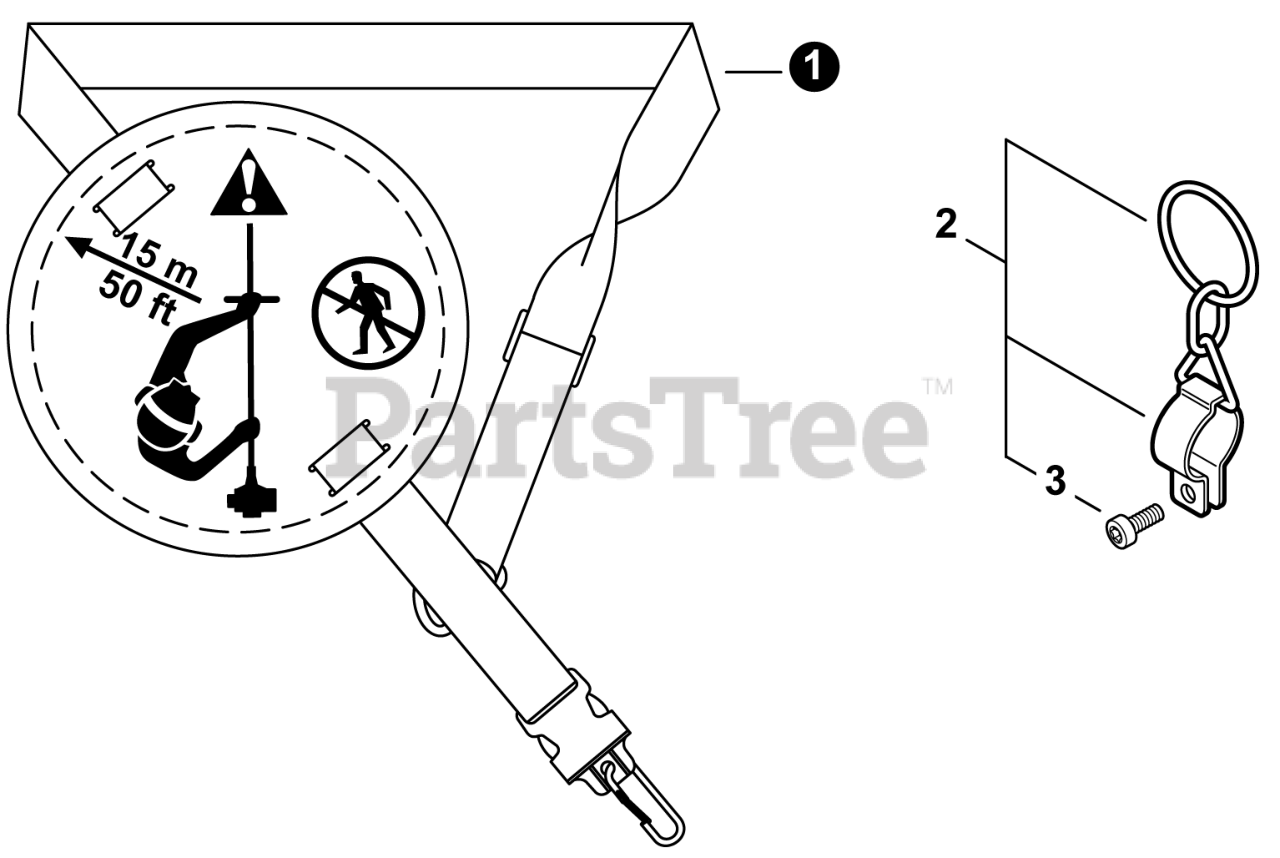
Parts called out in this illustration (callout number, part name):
1	HARNESS, SHOULDER
2	HANGER SET, HARNESS
3	BOLT, TORX 5x12
